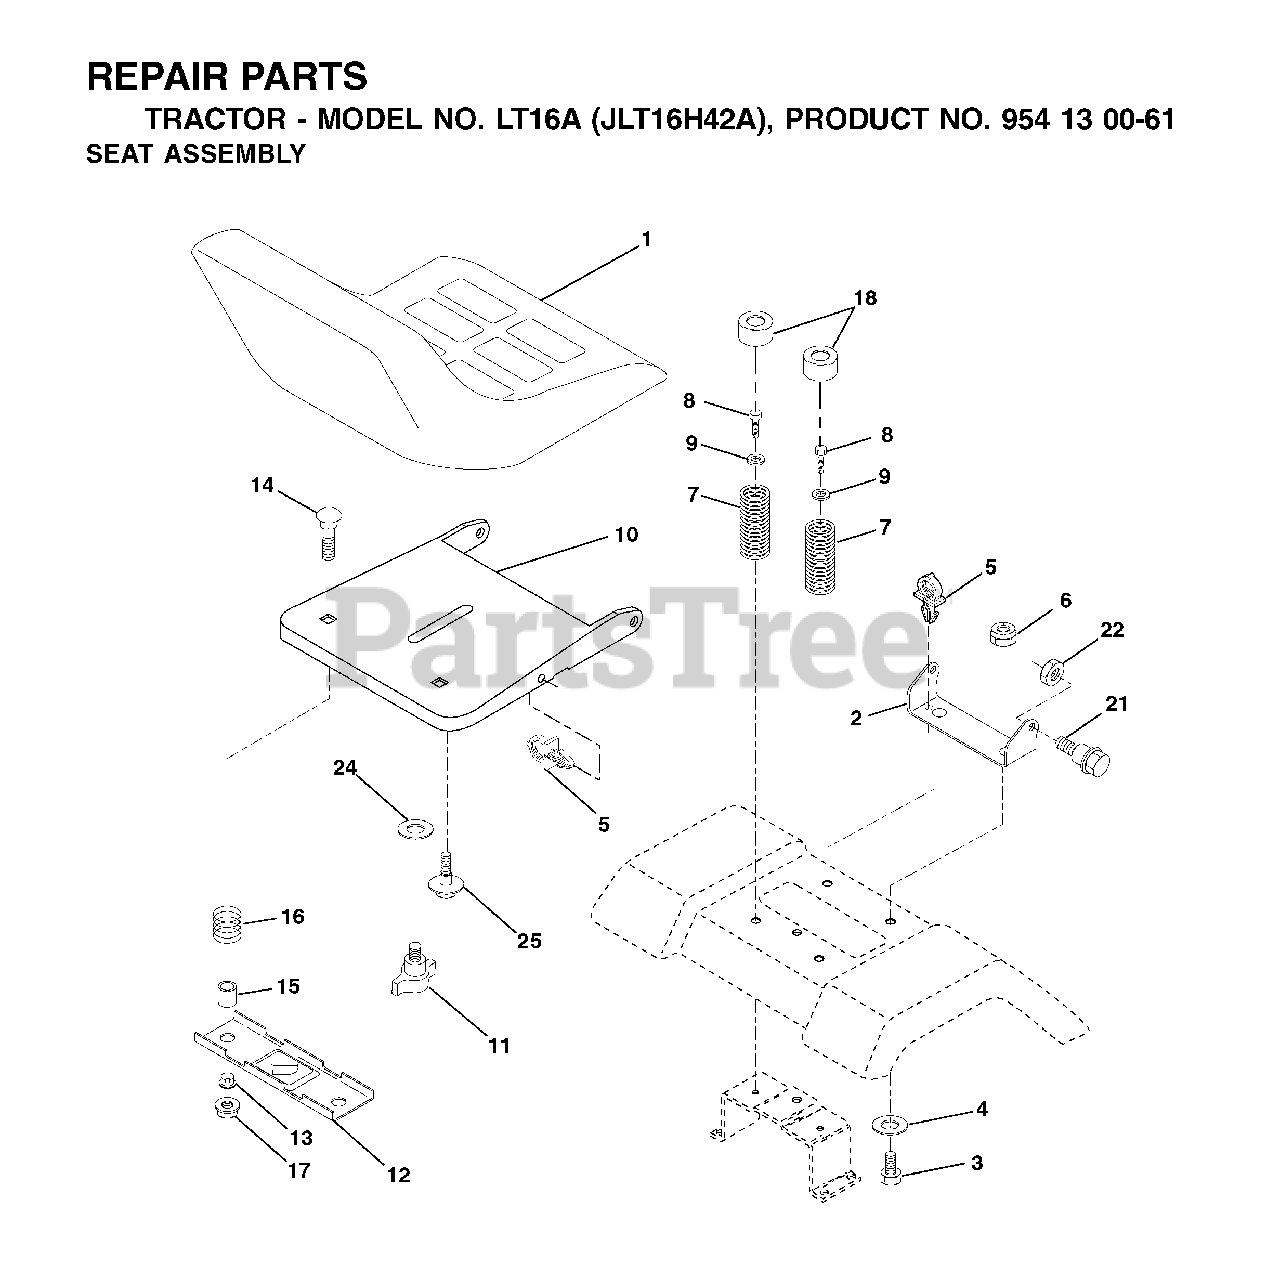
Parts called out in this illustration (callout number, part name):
2	SEAT PIVOT BRKT
4	WASHER PM
5	PUSH CLIP
6	NUT
7	SPRING COMPRESSION
8	SCREW 3/8-16X1
9	WASHER
10	PAN SEAT
11	KNOB.SEAT.ADJ.WINGNUT
12	BRKT SWITCH
14	BOLT.ROUND.HEAD.SQUARE.NECK
15	SPACER SPLIT 28X.96
17	NUT T
18	CAP SPRING
21	BOLT.SHOULDER.5/16-18
22	NUT.71038.31-18.HEX.NYLOCK
25	BOLT,SHOULD
